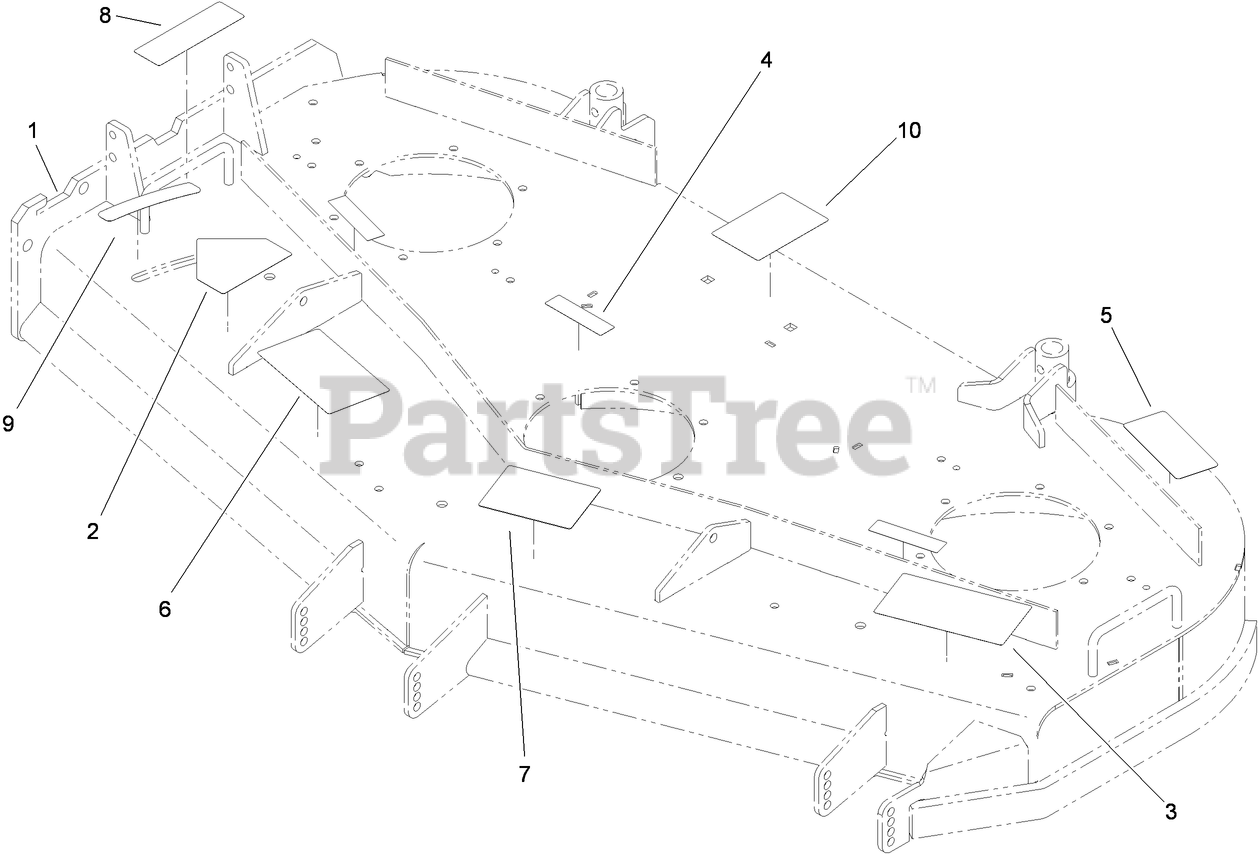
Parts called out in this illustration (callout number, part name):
1	52 INCH DECK ASM
2	DECAL-DANGER
3	DECAL-DANGER, THROWN OBJECT
4	DECAL-COVER, MISSING
5	DECAL-TORQUE
6	DECAL-ADJUSTMENT, BAFFLE
7	DECAL-SCALP, ANTI
8	DECAL-WARNING
9	DECAL-SETTING, BAFFLE
10	DECAL-ROUTING, BELT
